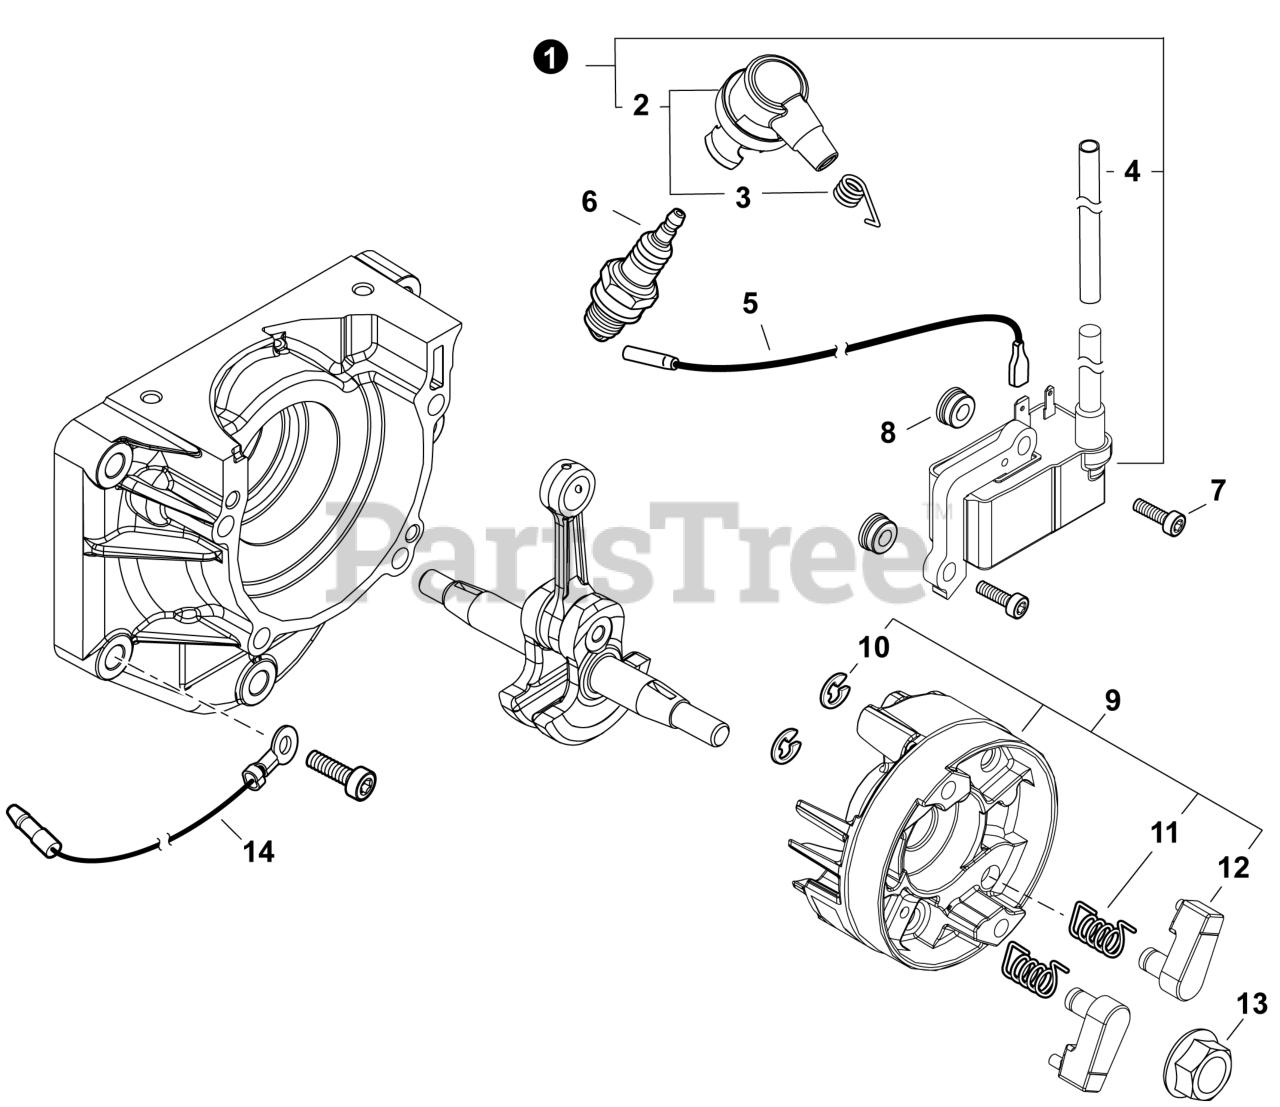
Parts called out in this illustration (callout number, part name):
1	KIT, IGNITION COIL
2	KIT, SPARK PLUG CAP
3	TERMINAL, SPARK PLUG
4	TUBE, INSULATOR
6	SPARK PLUG - CMR7H
7	BOLT 4x20
8	COLLAR 4
9	FLYWHEEL
10	E-RING
11	SPRING, RETURN
12	PAWL, STARTER
13	NUT, FLANGE 10x1.25
